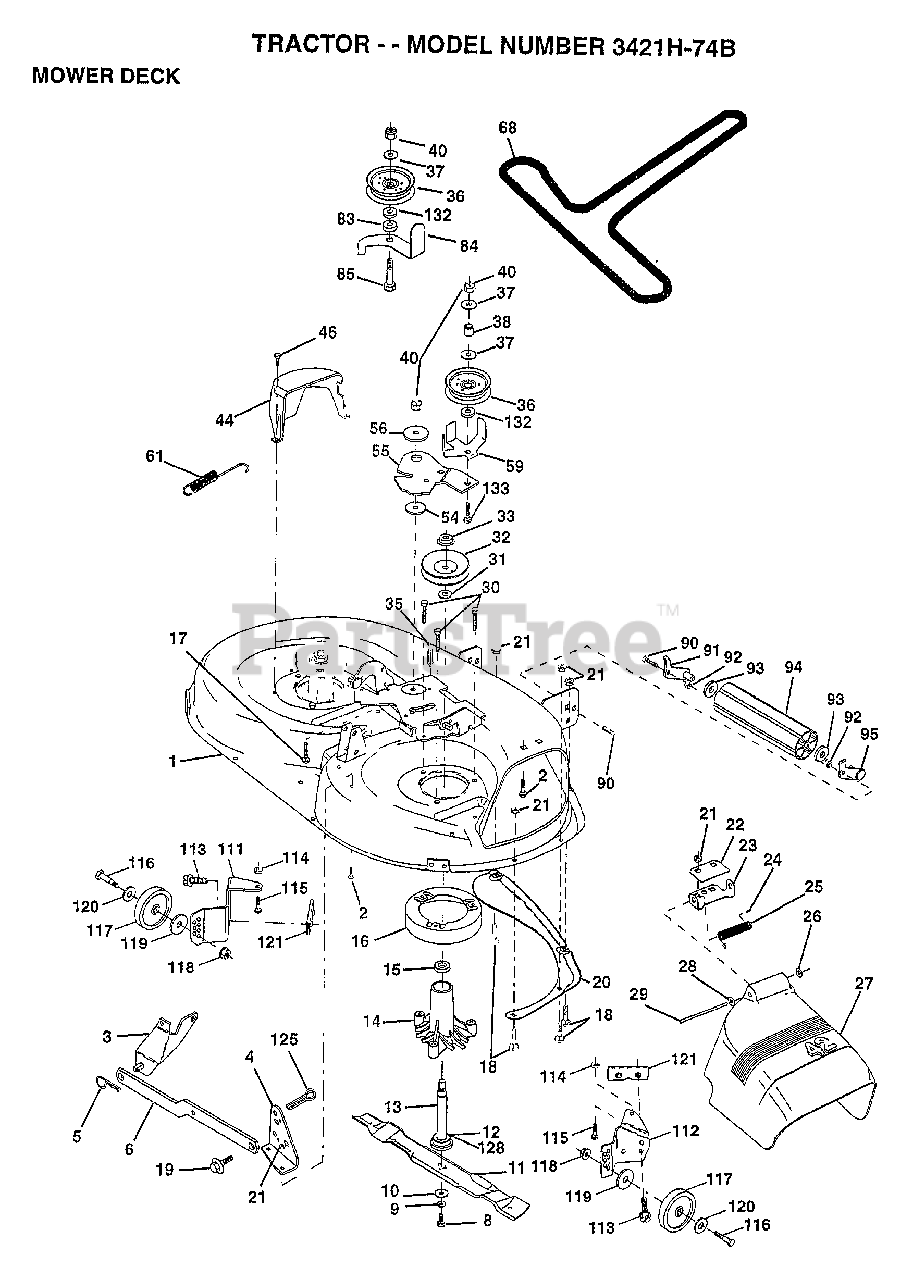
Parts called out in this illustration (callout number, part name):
1	DECK.WELD.42.
2	BOLT
3	BRKT ASM SWAY BAR
4	BRKT DECK SW BAR
8	BLADE BOLT
10	WASHER.HARD.BLADE
11	"BLADE.42"" HIPERF"
12	BEARING.BALL
14	HSG ASM MANDREL
15	BEARING
16	STRIPPER RND MWR
17	BOLT CARRIAGE
18	BOLT
19	BOLT SHD 5/16-18
22	STIFFENER BRKT
23	DEFLECTOR BRKT
24	CAP-SLEEVE LT
25	SPRING TORSION
26	NUT PUSH M
27	DEFLECTOR.SHIELD
28	WASHER
29	HINGE ROD
31	WASHER
32	PULLEY.MANDREL.42
34	BOLT
35	XMAS TREE FASTNER
36	FLAT IDLER PULLEY
37	WASHER
44	GUARD MAND LH BLK
46	SCREW.1/4-20X5/8
54	HARDENED WASHER
56	SPACER RETAINER
59	GUARD IDLER TUV
61	SPRING.EXTENSION
68	BELT.V.T-PATH
83	WASHER
84	"KEEPER-BELT,FIXED"
85	BOLT RDHD 3/8-16
90	BOLT
92	NUT
93	WASHER
111	BRACKET.GWHL.LH.
112	BRACKET.GWHL.RH.
113	SCREW
116	BOLT M
117	WHEEL.GAGE.BLK.PL
118	LOCKNUT
119	WASHER
120	WASHER
121	BRACKET.EXTRD.GWL
128	WASHER.FELT.
132	WASHER GT
